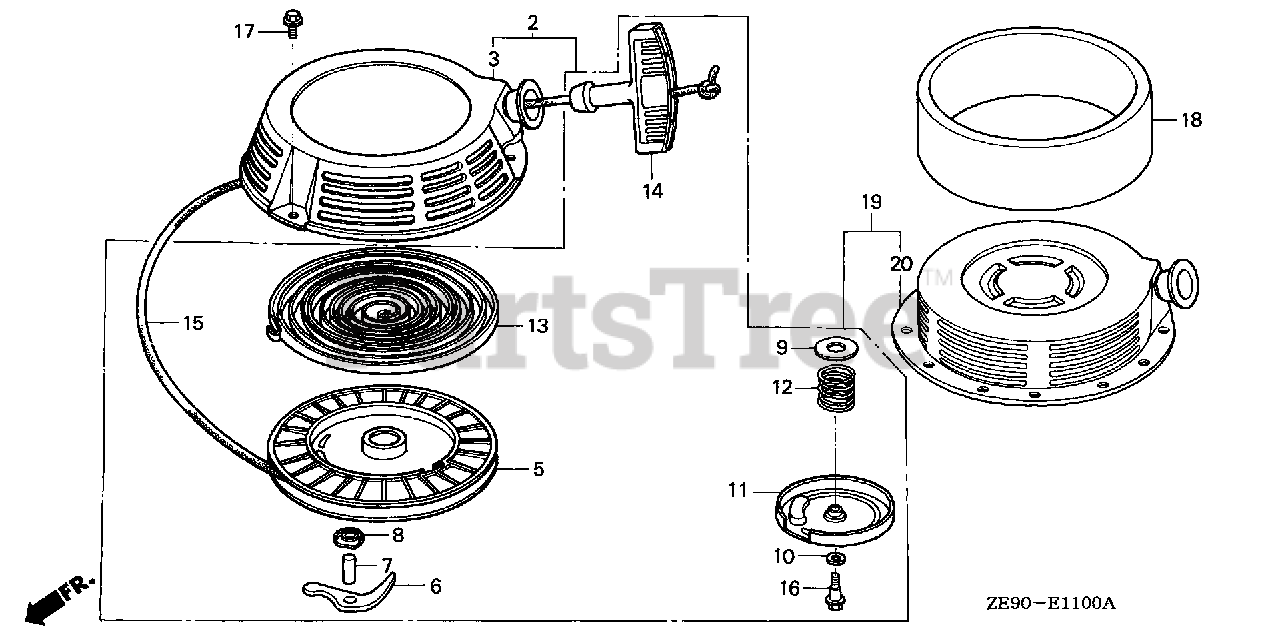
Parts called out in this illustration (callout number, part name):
5	REEL, STARTER
6	RATCHET, STARTER
7	SHAFT, RATCHET (NOT AVAILABLE)
8	PLATE, GUIDE
9	PLATE A, FRICTION
10	PLATE B, FRICTION
11	COVER, STARTER REEL
12	SPRING, FRICTION (D=18.5MM / L=20.5MM)
12	SPRING, FRICTION (D=13.0MM / L=16.3MM)
13	SPRING, RETURN
14	GRIP, STARTER
15	ROPE, STARTER (N/A: USE ALT P/N 08560-ZG921-11)
16	BOLT, REEL COVER
17	BOLT, FLANGE (6X10) (NOT AVAILABLE)
17	BOLT, FLANGE (6X8)
18	FILTER, AIR
19	STARTER ASSY., RECOIL *R8* (BRIGHT RED)
20	CASE, RECOIL STARTER *R8* (BRIGHT RED) (NOT AVAILABLE)
